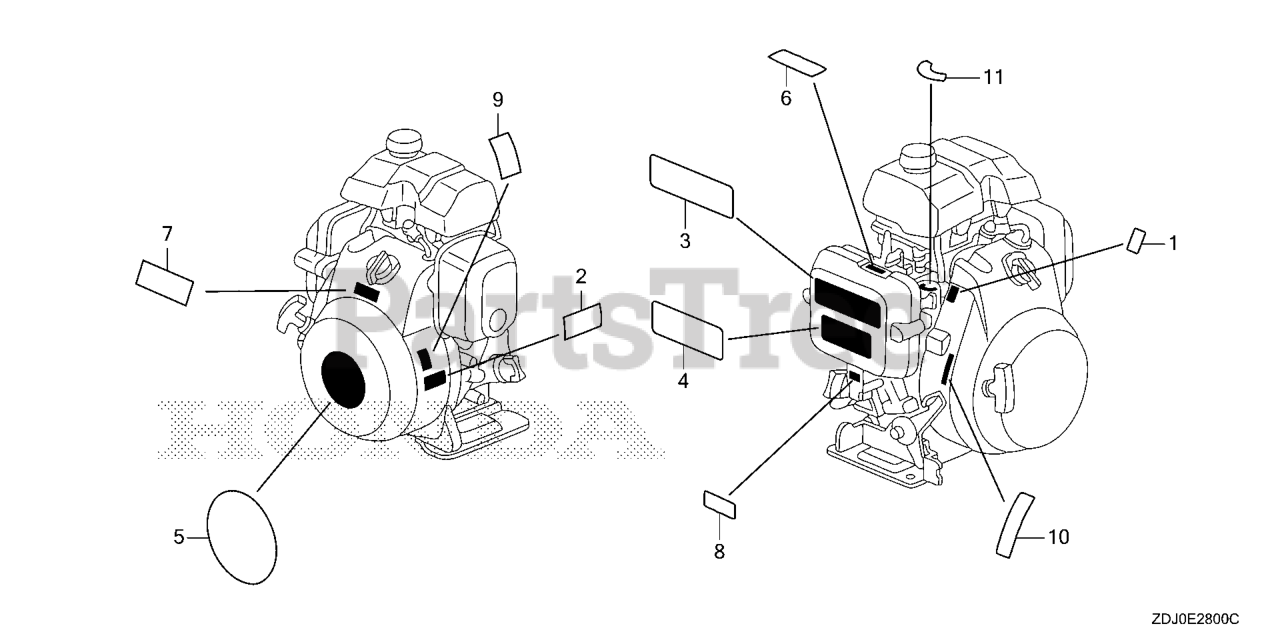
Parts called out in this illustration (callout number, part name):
3	MARK, OPERATOR CAUTION (PICTOGRAPH)
6	MARK, CHOKE INDICATION
8	MARK, TYPE (QXBR)
10	MARK, THROTTLE INDICATION
11	MARK, PETCOCK (EXTERNAL)
